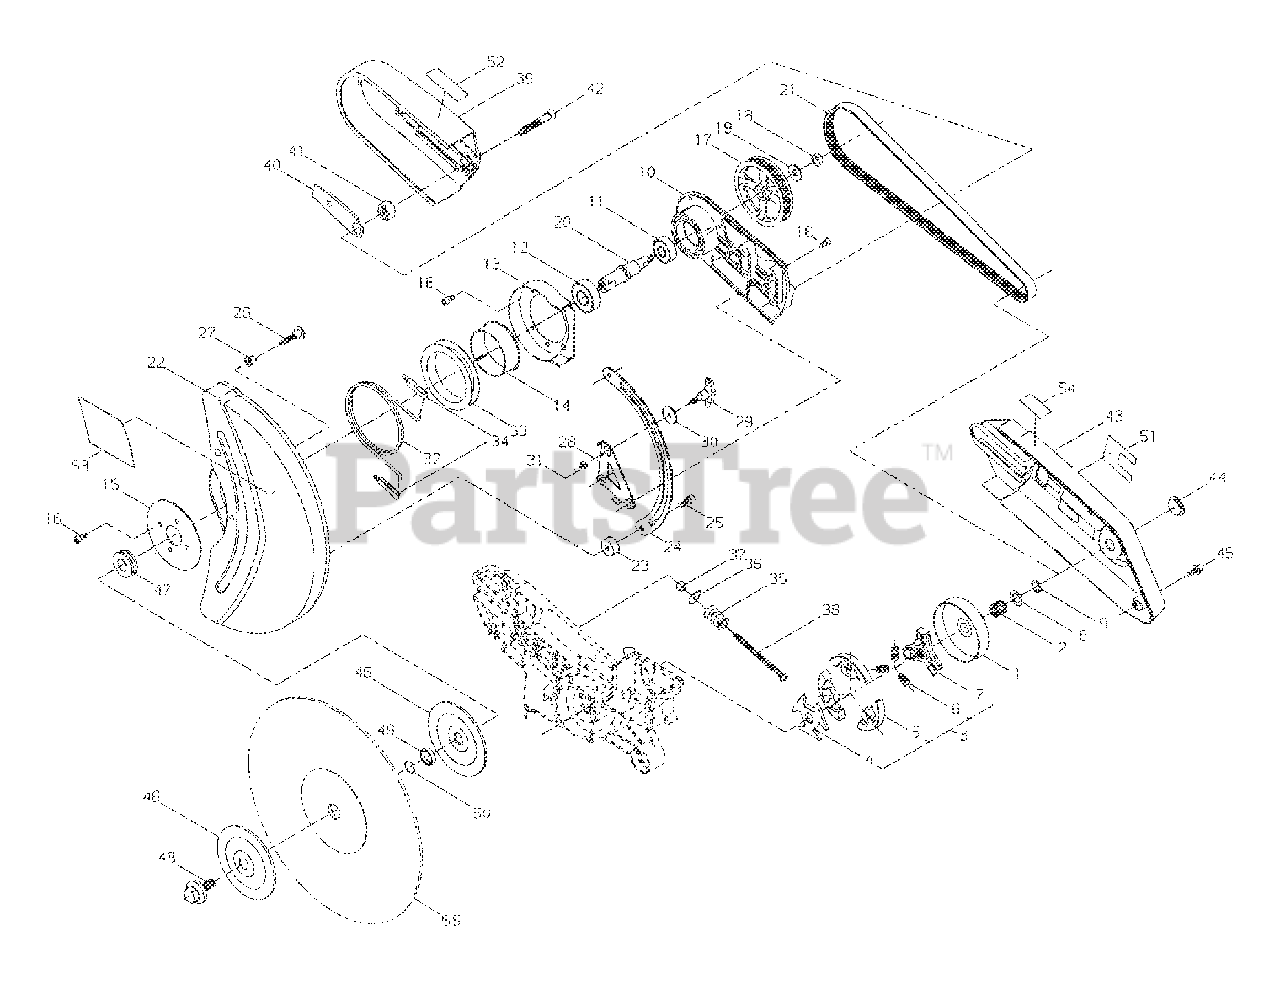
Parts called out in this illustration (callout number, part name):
1	DRUM, CLUTCH
2	BEARING, NEEDLE
3	CLUTCH ASSY
4	BOSS, CLUTCH A
5	SHOE, CLUTCH
6	SPRING, CLUTCH
7	BOSS, CLUTCH B
8	THRUST PLATE
9	RING, SNAP
10	BEARING CASE
11	BEARING, BALL 6201
12	BEARING, BALL 6203
13	PLATE, SPRING
14	RING
15	BEARING PLATE
16	BOLT 5×16
17	PULLEY, DRIVE
18	NUT M8
19	COLLAR
20	DRIVESHAFT
21	DRIVE BELT
22	GUARD, WHEEL
23	COLLAR
24	SLIDE PLATE
25	BOLT 6×20
26	BOLT, CLUTCH
28	PLATE, LOCK
29	KNOB
30	WASHER Ø23ר6.5×2 MM
31	NUT
32	SPRING
33	GUIDE, SPRING
34	SPRING HOLDER
35	SPRING
36	WASHER
37	NUT
38	SCREW
39	PULLEY COVER
40	TENSION PLATE
41	TENSION BLOCK
42	BOLT
43	COVER, CLUTCH
44	PLUG
45	BOLT, ADHESIVE M5×14
46	FLANGE
47	COLLAR
48	BOLT - FLANGE
49	COLLAR
50	RING, RETAINING
51	LABEL - TRADE
52	LABEL - INSTRUCTION
53	LABEL - CAUTION
54	LABEL -ARROW
55	CUT OFF WHEEL
